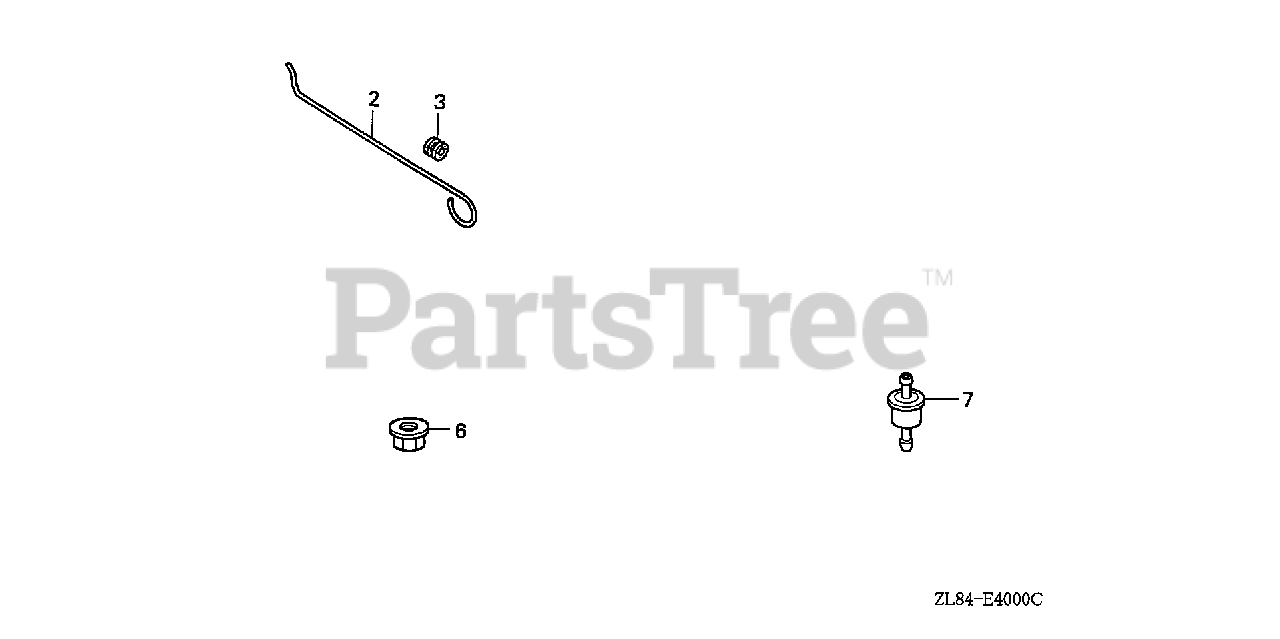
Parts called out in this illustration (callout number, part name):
2	ROD, CHOKE CONTROL
3	GROMMET, CHOKE ROD
6	NUT, FLANGE (6MM)
7	FILTER, FUEL
